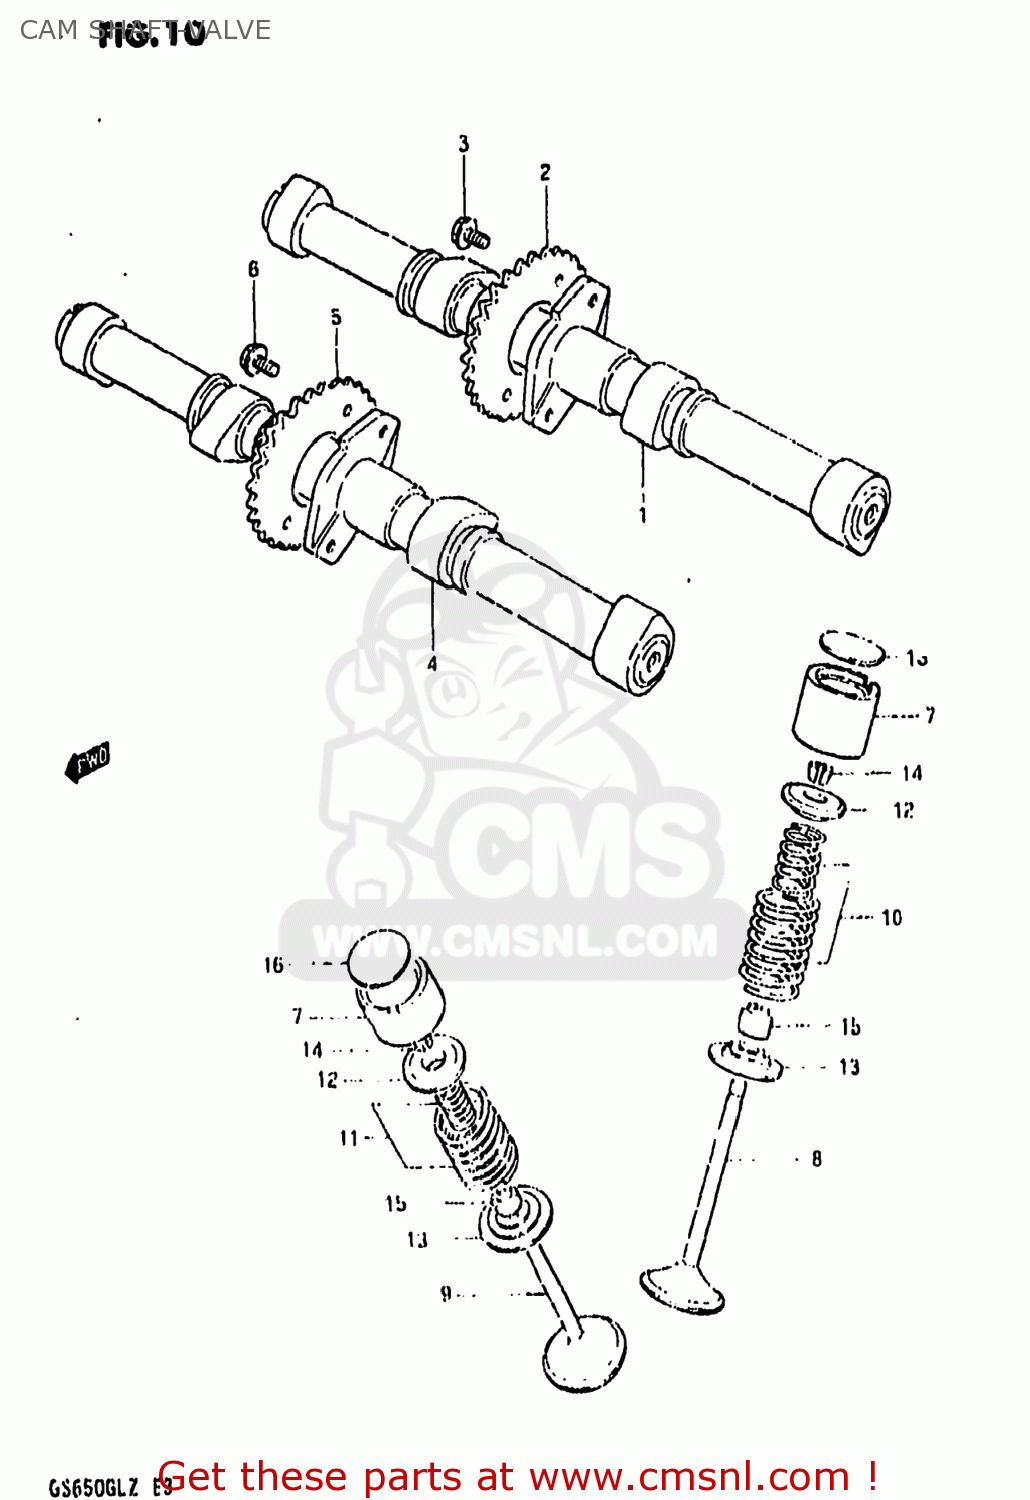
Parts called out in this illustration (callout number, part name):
1	CAMSHAFT,INTAKE
2	SPROCKET,INTAKE CAMSHAFT
3	BOLT(7X11)
4	CAMSHAFT,EXHAUST
5	SPROCKET,EXHAUST CAMSHAFT
6	BOLT(7X11)
7	TAPPET
8	VALVE,INTAKE
9	VALVE,EXHAUST
10	SPRING SET,VALVE
11	SPRING SET,VALVE
12	RETAINER,VALVE SPRING
13	SEAT,VALVE SPRING
14	COTTER VALVE
15	SEAL,OIL(7X14.4X9)
16	SHIM,TAPPET
17	SHIM SET,TAPPET
18	CASE
